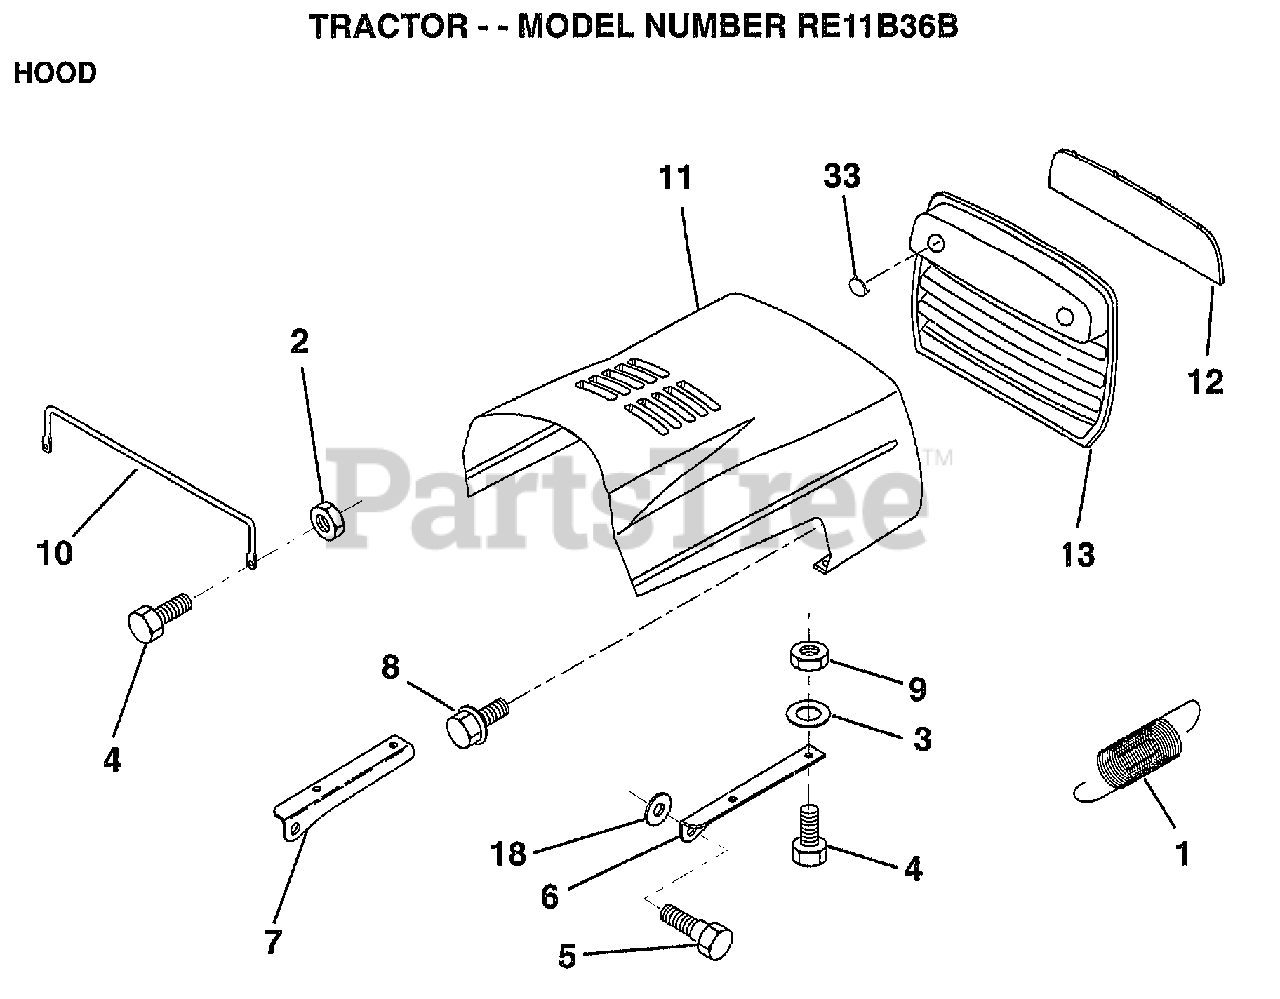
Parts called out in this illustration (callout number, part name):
1	EXT SPRING
2	NUT
3	WASHER
5	BOLT.SHLD.5/16-18
6	BRKT HOOD RH
7	BRKT HOOD LH
8	"SCREW,HWHD.HI-LO#13-16X3/4"
9	NUT
10	"BRACE,HOOD"
11	HOOD
12	LENS
13	GRILL
18	WASHER
